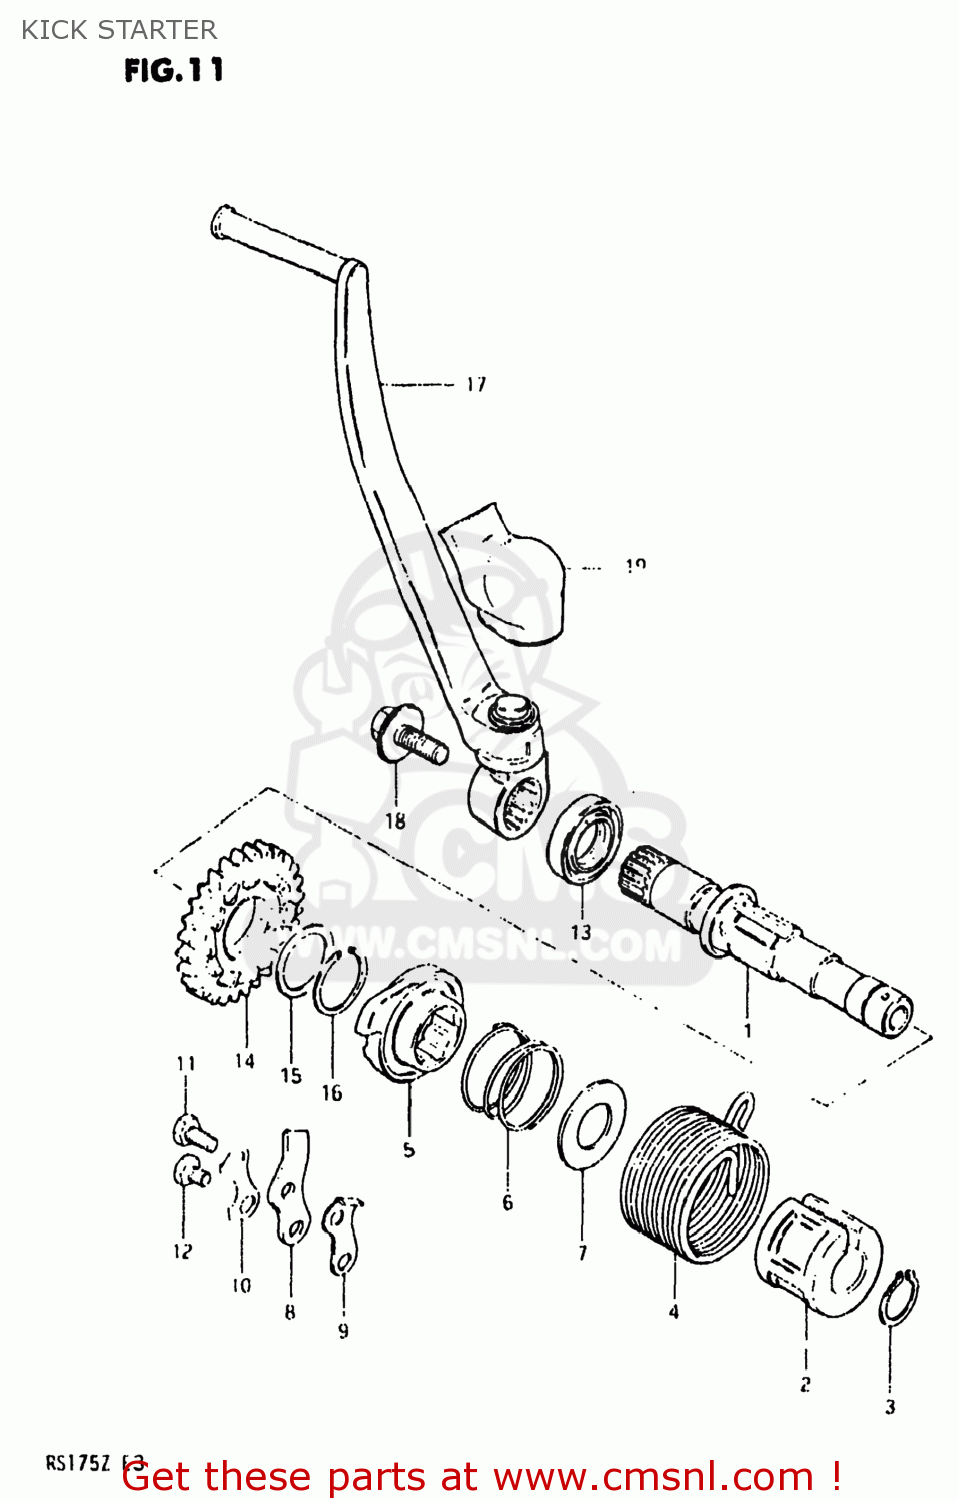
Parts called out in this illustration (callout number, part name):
1	SHAFT,KICK STARTER
2	GUIDE,KICK STARTER SFT SPRING
3	CIRCLIP
4	SPRING
5	STARTER,KICK
6	SPRING
7	WASHER
8	GUIDE,KICK STARTER
9	STOPPER,KICK STARTER
10	WASHER
11	BOLT, UPPER
12	BOLT
13	SEAL,OIL(20X27X5)
14	GEAR,KICK STARTER DRIIVE
15	SHIM
16	CIRCLIP
17	LEVER ASSEMBLY,KICK STARTER
18	BOLT(8X14)
19	COVER,KICK LEVER JOINT
